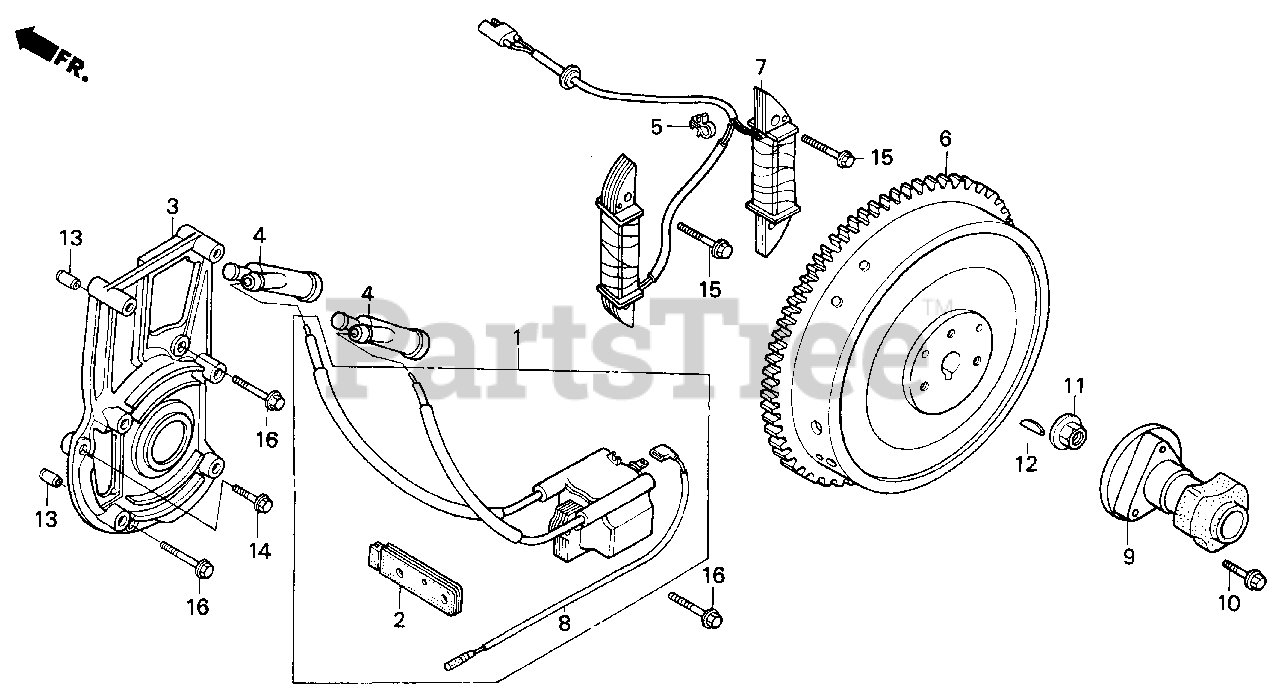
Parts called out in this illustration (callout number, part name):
1	COIL ASSY., IGNITION
2	GROMMET, IGNITION WIRE
3	STAY, IGNITION SYSTEM
4	CAP ASSY., NOISE SUPPRESSOR (NICHIWA Y-EZ RTFM256)
5	CLIP, IGNITION WIRE (8MM)
7	COIL ASSY., CHARGE (D.C.135V 90-130W)
8	WIRE, ENGINE STOP
9	DAMPER A, PROPELLER SHAFT
10	BOLT, UBS (8X33)
11	NUT, SPECIAL (16MM)
12	KEY, SPECIAL WOODRUFF (25X18)
13	PIN A, DOWEL (8X10)
14	BOLT, FLANGE (6X22)
15	BOLT, FLANGE (6X32)
16	BOLT, FLANGE (6X28)
16	BOLT, FLANGE (6X32)
